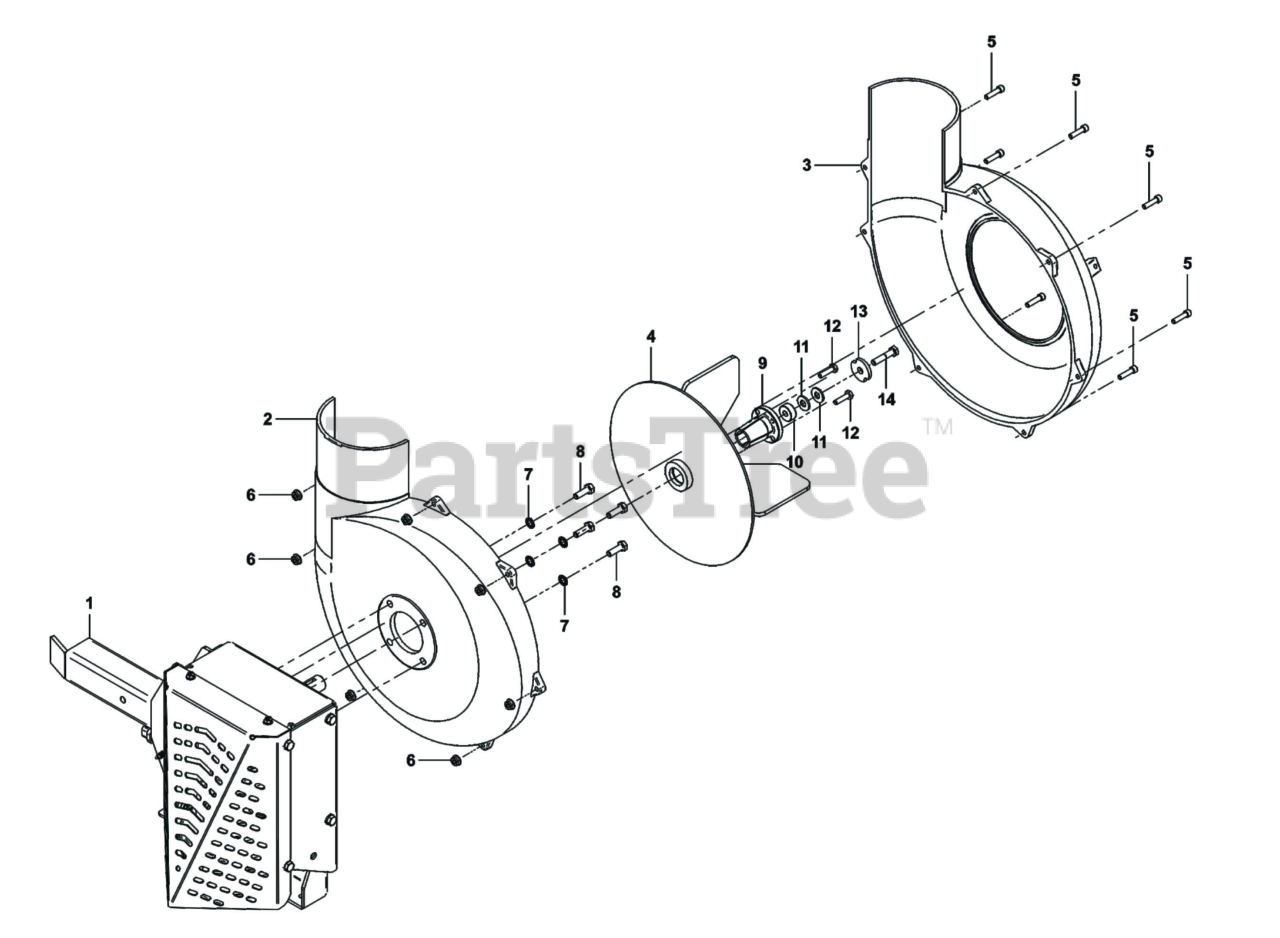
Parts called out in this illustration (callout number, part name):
1	DRIVE ASSEMBLY BASE
2	BACK BLOWER HOUSING
3	FRONT BLOWER HOUSING
4	IMPELLER-4 BLADED
5	1/4"-20x1" SHCS/Zinc/GR8
6	NUT-FLANGE 1/4-20
7	I/T TOOTH LOCK WASHER
8	HEX SCREW HEAD 5/1
9	TAPER LOCK BUSHING 7/8"
10	SPACER BUSHING
11	FLAT WASHER
12	BOLT-HEX 1/4-20 X
13	DBL INDENTED WASHER 3/8"
14	SCREW 5/16"-24 X 1.5" GR8
